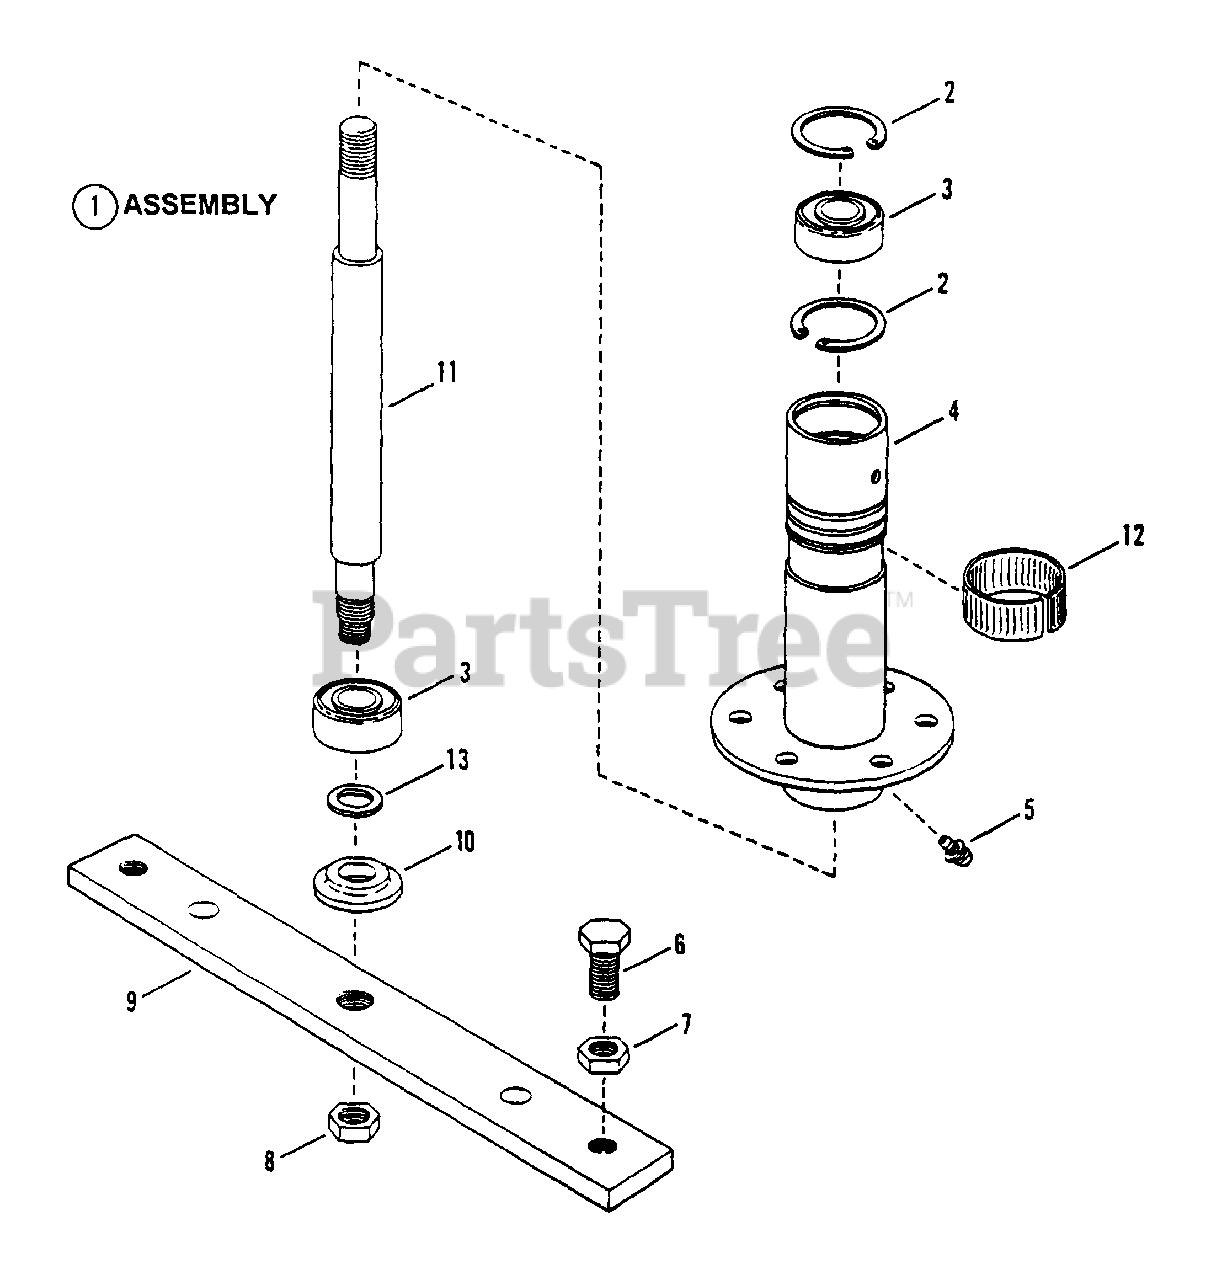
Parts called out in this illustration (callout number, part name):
1	ASSEMBLY, Spindle Housing
2	RING, Retaining
3	BEARING, Spindle
4	HOUSING, Spindle
5	FITTING, Lube (Press fit for .187 hole-no ball)
6	SCREW, 1/2-20 x 1" Hex Head Cap (GR. 5)
7	NUT, 1/2-20 Hex Jam
8	NUT, 5/8-18 Hex Lock
9	HOLDER, Blade
10	WASHER, Spindle
11	SPINDLE, Shaft (10.237" Long)
12	RING, Tolerance
13	WASHER, 3/4 Shim
